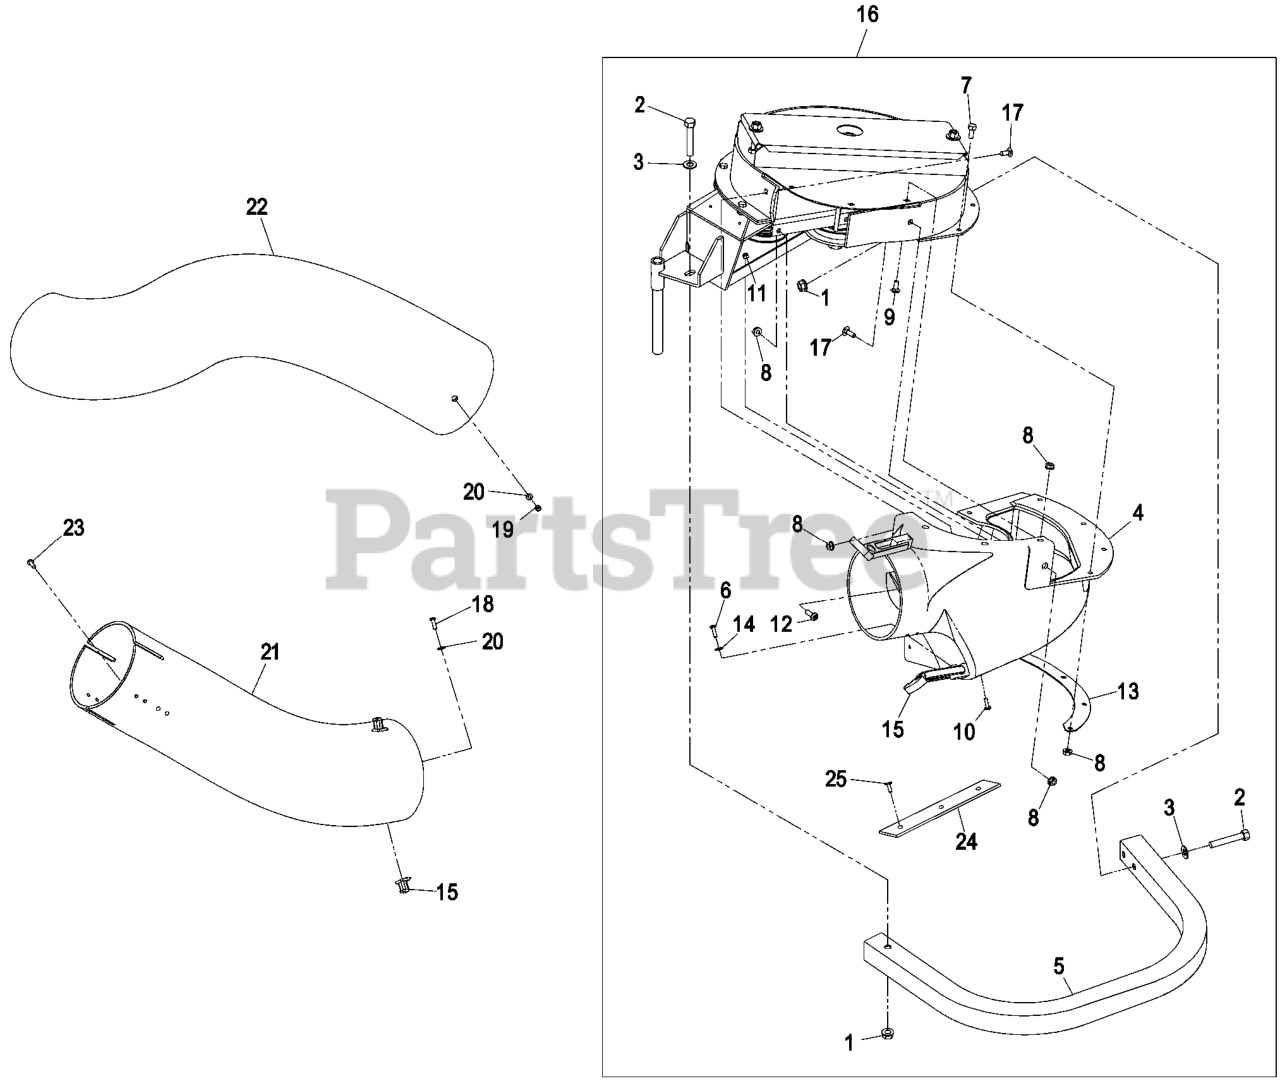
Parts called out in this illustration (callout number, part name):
1	NUT-HHF, WHIZ
2	SCREW-HH
3	WASHER-FLAT
4	ASM,BLOWER CHUTE SMALL
6	SCREW-PPH
7	SCREW-HH
9	SCREW-CARR
10	SCREW-HEAD, TRUSS
13	PLATE-BACKING, BLOWER
14	WASHER-FLAT
15	LATCH DRAW
16	ASM,BLOWER 44/48 - SERVIC
17	BOLT-CARR
18	SCREW-PPH
19	NUT-LOCK, NI
20	WASHER-FLAT
21	KIT,LOWER TUBE
22	TUBE,UPPER 46/50
23	SCREW-HWH
24	PLATE-REINFORCEMENT
25	RIVET-BLIND
